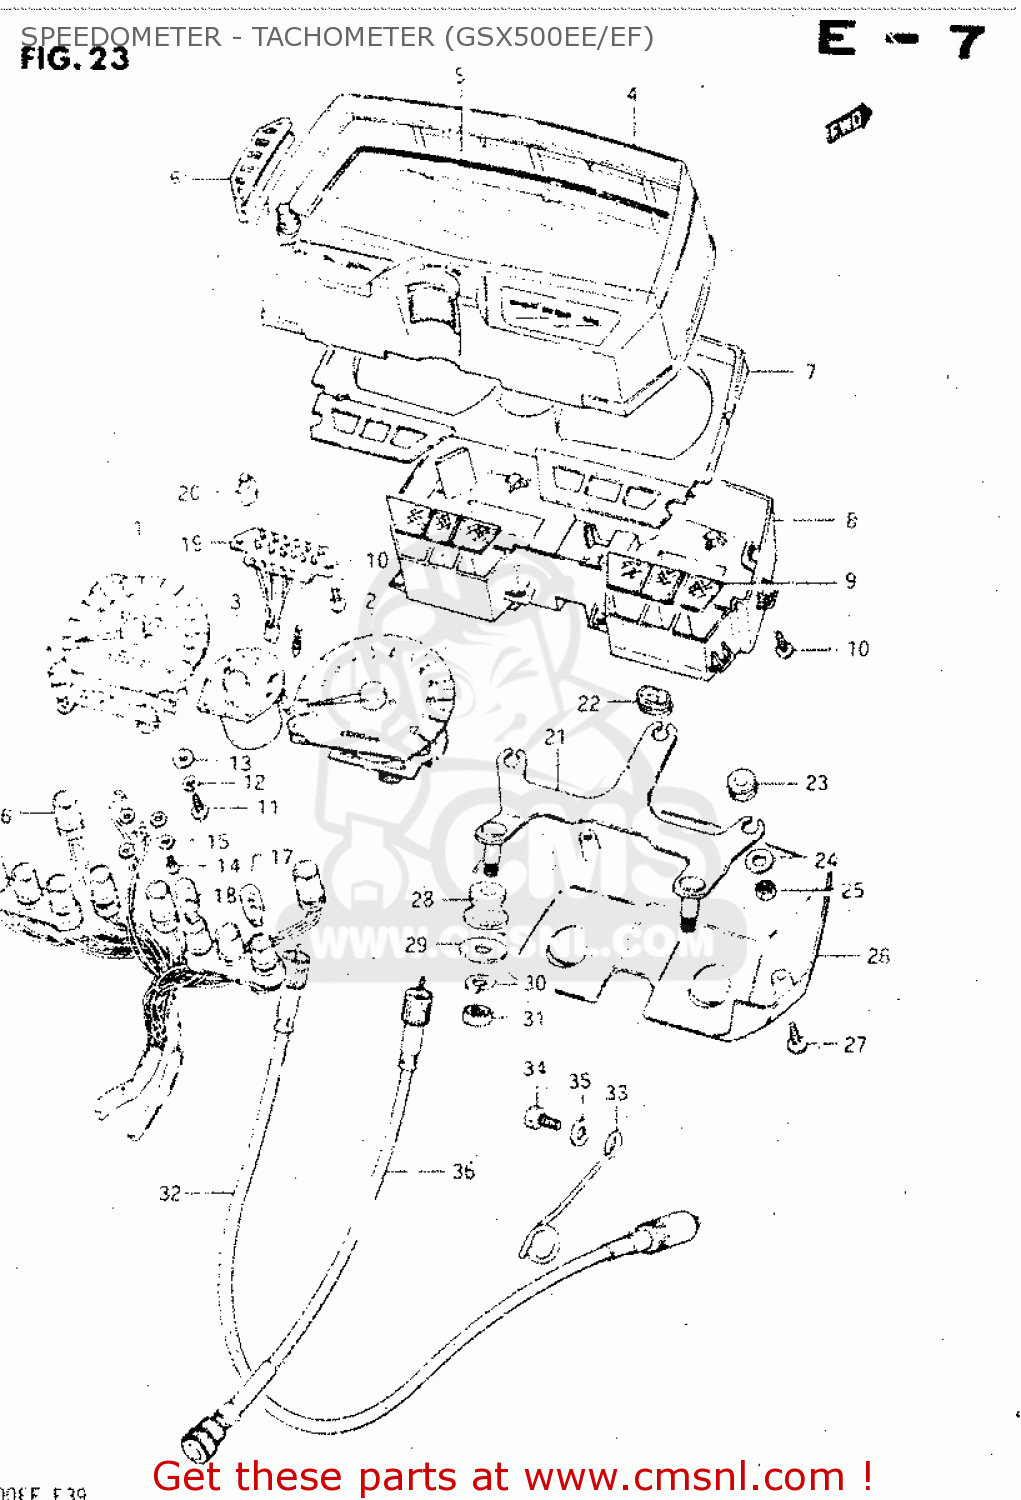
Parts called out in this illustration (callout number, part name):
1	SPEEDOMETER (KILO)
2	METER,TACHOMETER
3	METER,FUEL
4	HOOD,METER
5	GLASS,SPEEDOMETER
6	CUSHION,METER CASE
7	PLATE,METER WINDOW
8	CASE,METER,INNER
9	LENS SET,PILOT
10	SCREW,GEAR INDICATOR
11	SCREW
12	LOCK WASHER
13	WASHER
14	SCREW
15	WASHER
16	SOCKET
17	BULB(12V3.4W,T10,BF175-01450A)
18	BULB(12V1.7W,T10,WB121)
19	SOCKET,GEAR INDICATOR
20	BULB(14V1.12W)
21	BRACKET,METER
22	CUSHION,METER
23	CUSHION,METER
24	WASHER,METER
25	NUT
26	COVER,METER,UNDER
27	SCREW
28	CUSHION,METER BRACKET
29	WASHER (8.5X20X1.6)
30	WASHER,LOCK,8.
31	NUT
32	CABLE ASSEMBLY,SPEEDOMETER
33	CLAMP,SPEEDOMETER CABLE
34	BOLT, UPPER
35	WASHER
36	CABLE ASSY,TACHOMETER
